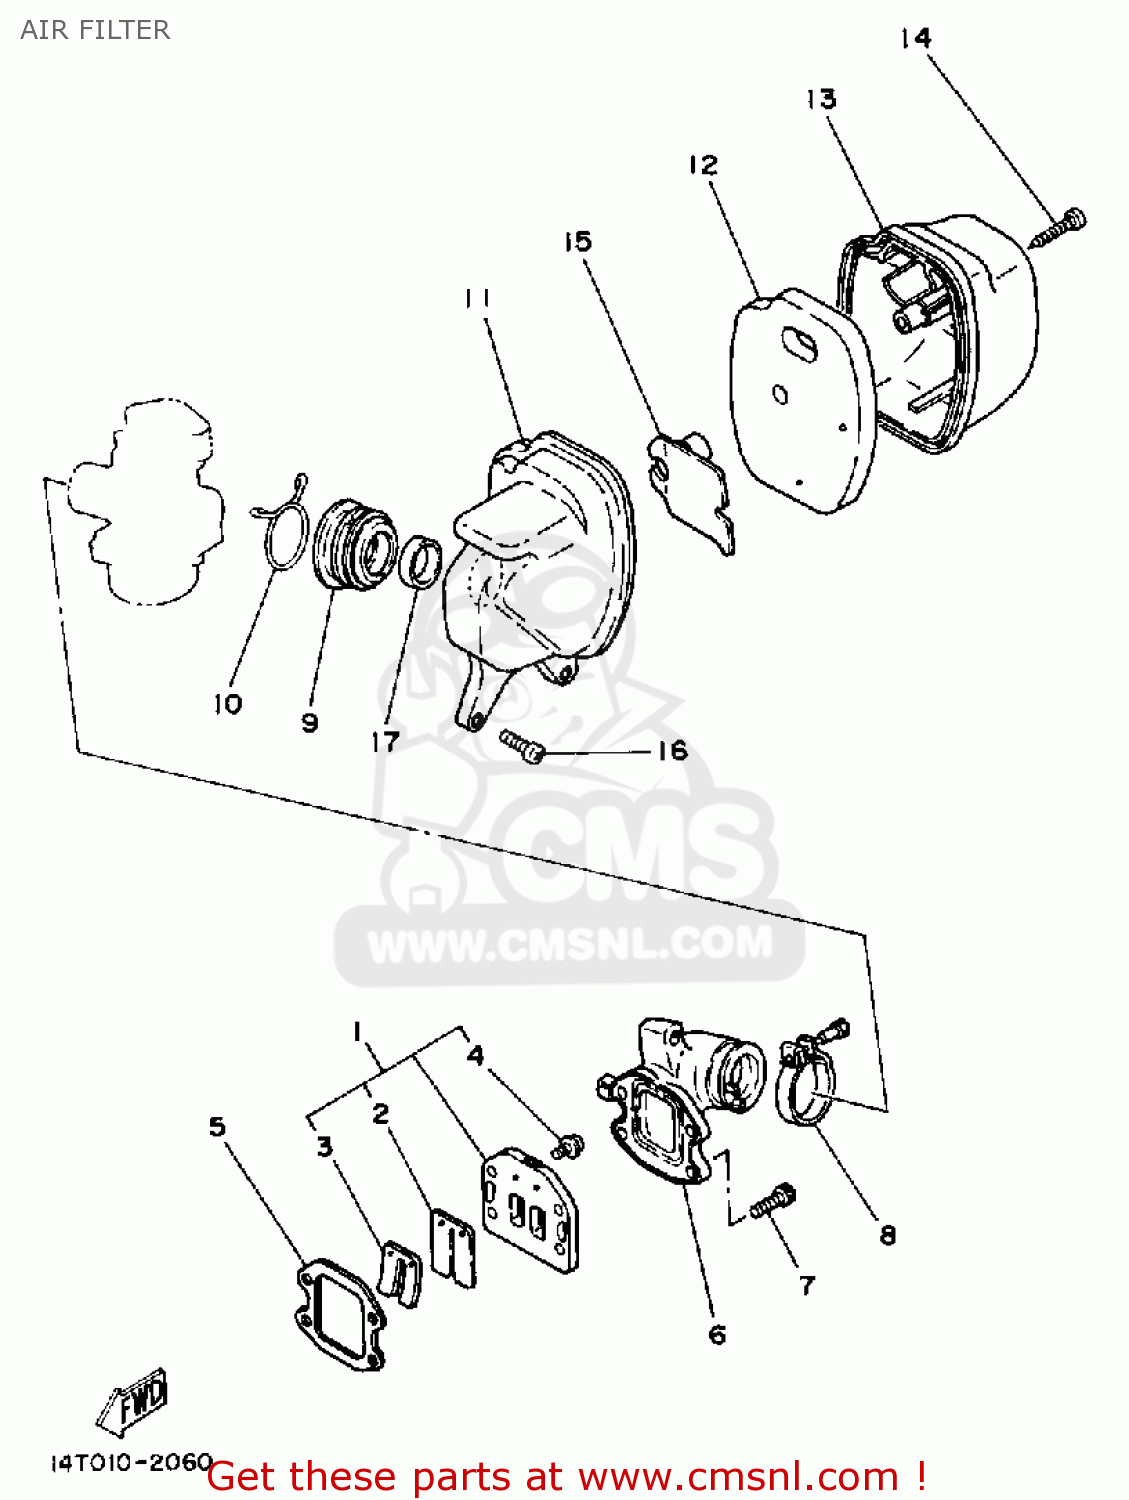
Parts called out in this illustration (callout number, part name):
1	REED VALVE ASSY
2	REED VALVE 1
3	STOPPER, REED VALVE
4	SCREW, PAN HEAD (J10)
5	GASKET, VALVE SEAT (NAS)
6	MANIFOLD, INTAKE
7	BOLT
8	CLAMP, HOSE (27V)
9	JOINT, AIR CLEANER 1
10	CLIP 296144550000
11	CASE, AIR CLEANER 1
12	ELEMENT, AIR CLEANER
13	AIR FILTER CASE ASSY
14	YBS83-530 SCREW,PANH.TAPPING
15	AIR FILTER CASE ASSY
16	SCREW PAN HEAD
17	AIR FILTER CASE ASSY
